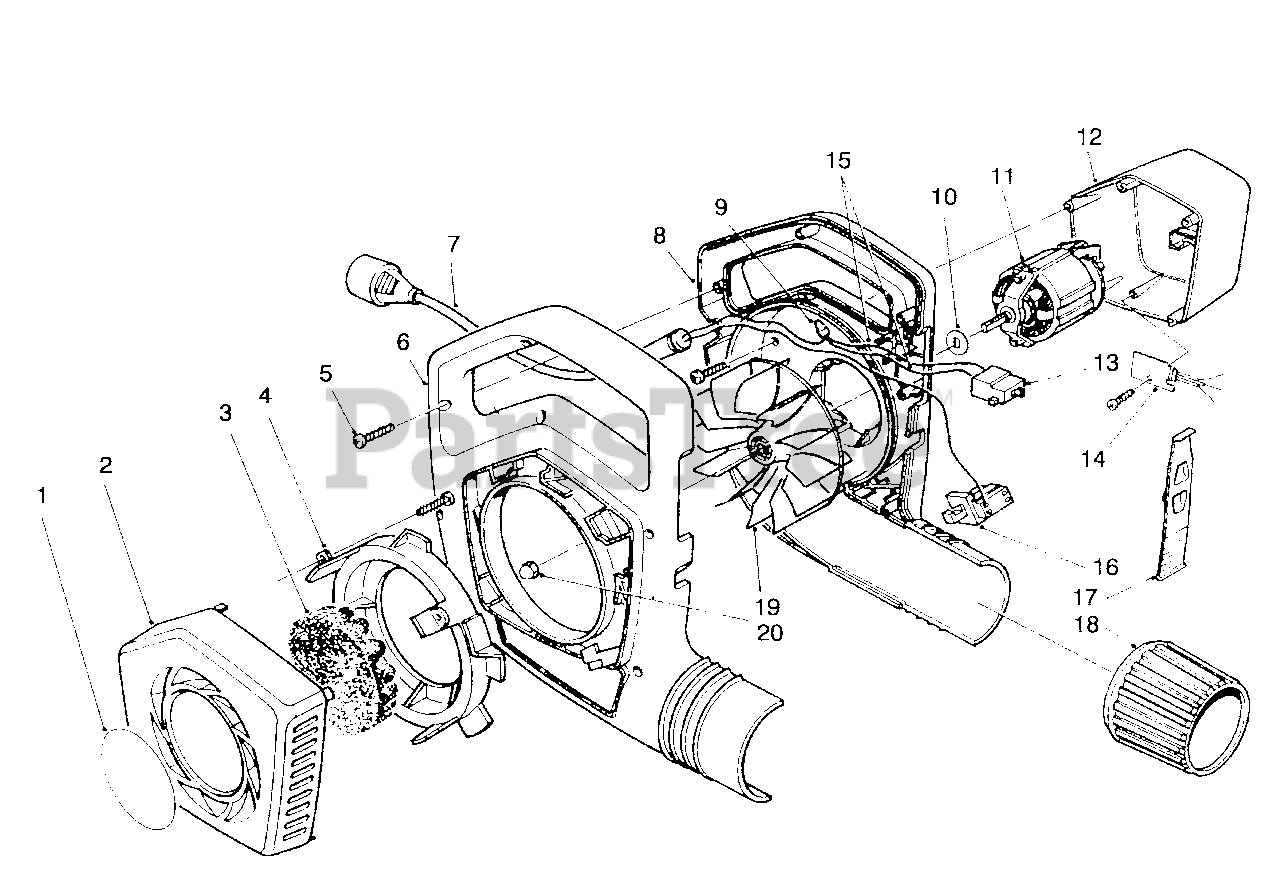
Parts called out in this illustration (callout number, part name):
1	Decal-Cover
2	Cover-Intake
3	Foam-Center
4	Ring-Coupling
5	Screw-Self Tapping
6	Housing-Blower, R.H.
7	Cord-Power Supply
8	Housing-Blower, L.H.
9	Connector-Wire
10	Washer-Impeller
11	Motor-Blower
12	Cover-Motor
13	Switch-2 Speed
14	Diode Assembly
16	Switch-Interlock
17	Switch-Cam, 2 Speed
18	Collar-Output
19	Impeller
20	Nut-Cap, Locking
